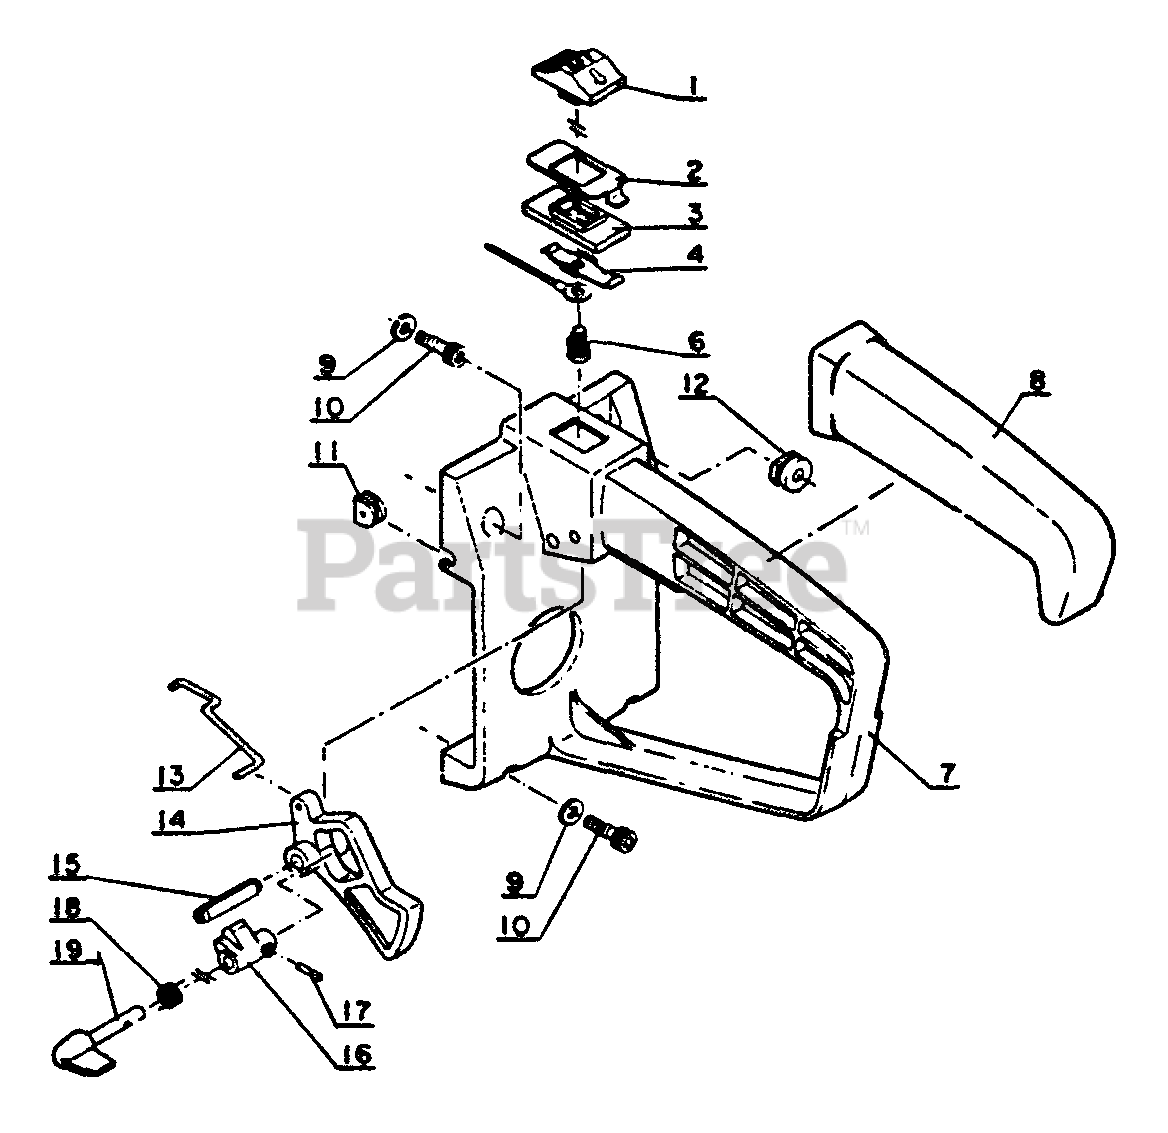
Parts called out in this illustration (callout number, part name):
1	SWITCH, IGNITION
2	PLATE, SWITCH
3	GUIDE, SWITCH
4	CONTACT, SWITCH
6	SCREW - 4×10
7	HANDLE - REAR
8	GRIP
9	WASHER 4 MM
10	SCREW - 4×18
13	ROD, THROTTLE
14	TRIGGER, THROTTLE
15	PIN, SPRING Ø5×25 MM
16	LOCKOUT, TRIGGER
17	PIN, SPRING 16×10
18	SPRING, THROTTLE LOCK
19	LEVER, THROTTLE
